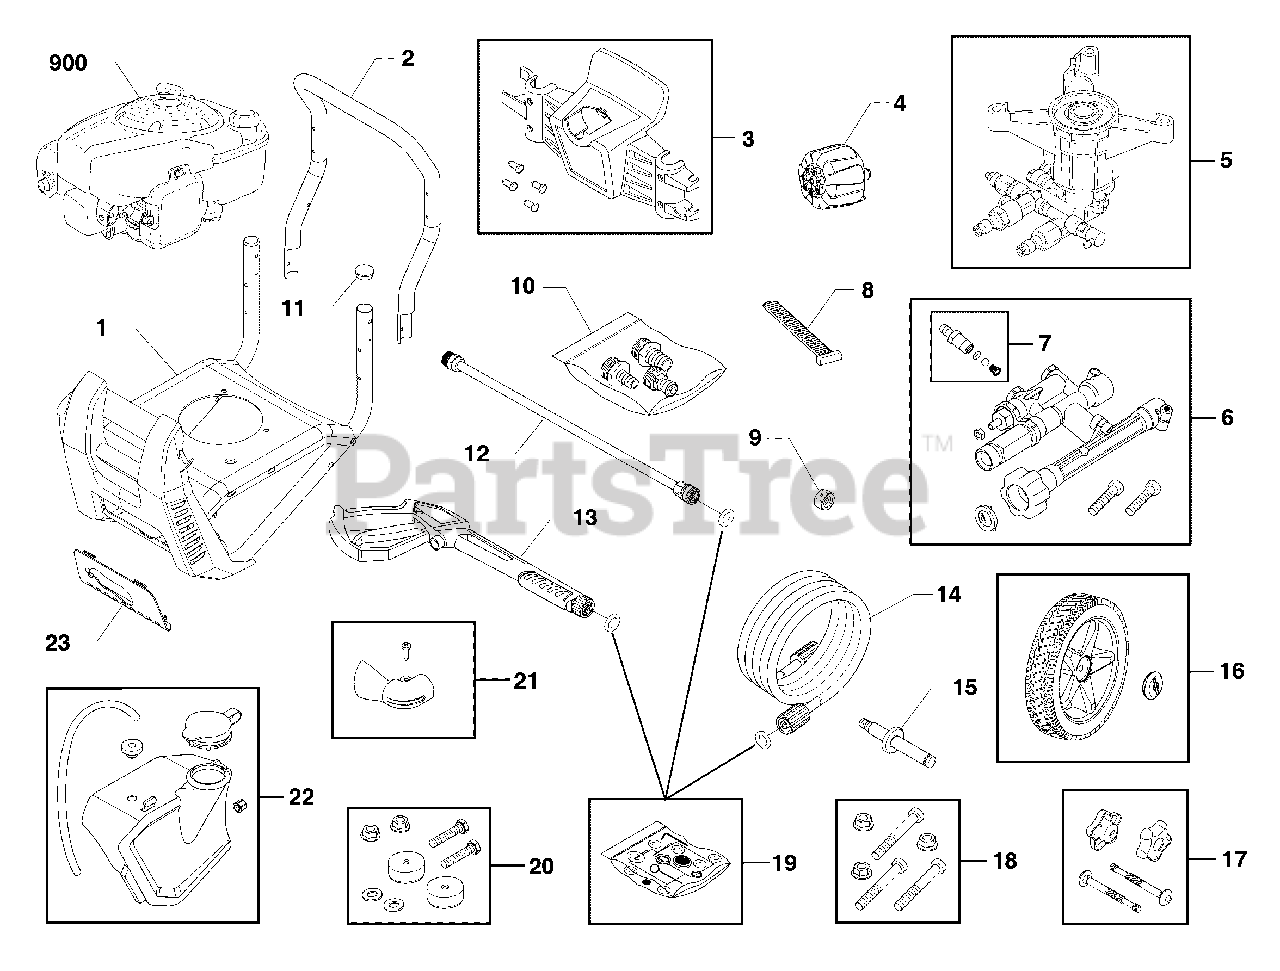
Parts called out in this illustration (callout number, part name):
5	PUMP
9	NUT, 3/8-16, Hex Center-Lock, GR B, Zinc/Clear
10	KIT-GARDEN HOSE
12	EXTENSION, QC
17	KIT, Hardware, Handle
18	KIT, Hardware, Pump Mounting
19	KIT-O-RING MAINTENANCE
20	KIT, Vibration Mount
21	DEFLECTOR-EXHAUST
22	TANK-CHEMICAL, RH
